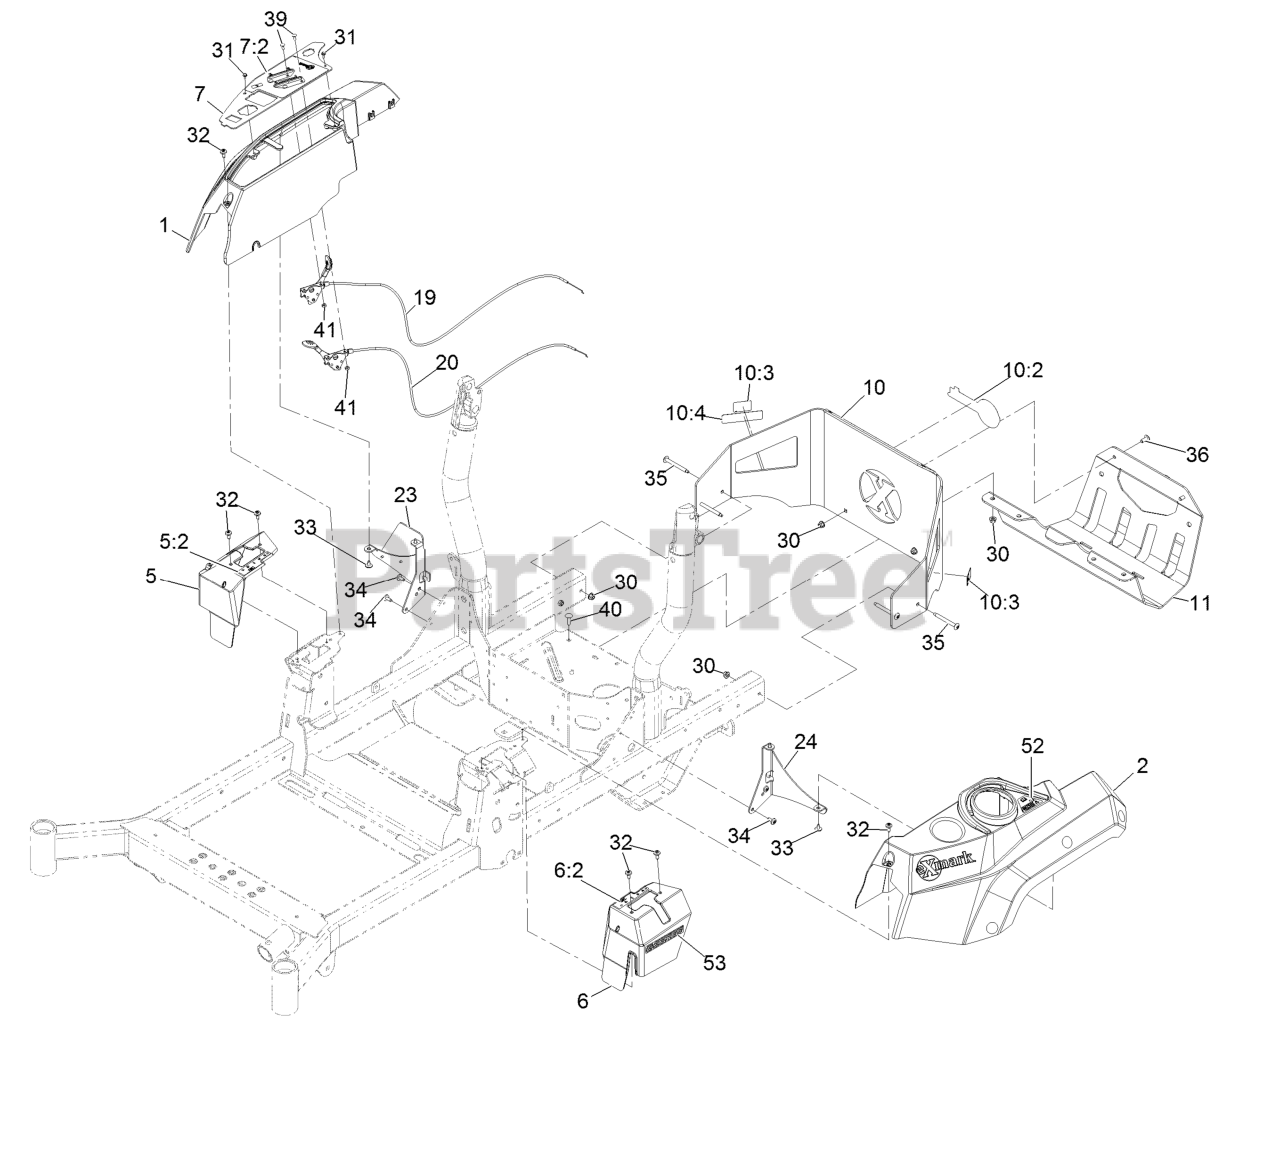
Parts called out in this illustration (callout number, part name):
1	Console, RH
2	Console, LH
5	Cover-Control, Motion (RH)
5:2	Decal-Control, Motion (RH)
6	Cover-Control, Motion (LH)
6:2	Decal-Control, Motion (LH)
7	Ctrl Panel ASM W/Decal
7:2	Decal-Control Panel
10	Rear Guard ASM
10:2	Decal-Exmark Logo
10:3	Decal-Warning
10:4	Decal-Arrester, Spark
11	Guard-Muffler
19	Cable-Control, Choke
20	Cable-Control, Throttle
23	Support-Console, RH
24	Bracket-Console, LH
30	Nut-Nyloc 5/16-18 Flg
31	Screw-HWH #10-14 X 1/2
32	Screw-1/4-20 X 1/2 Tf Torx Plus
33	Screw-HWH #10-14 X 1/2 Torx
34	Screw-1/4-20 X .65 Torx Plus
35	Screw-Truss HD 5/16-18 X 2 3/4 Torx Plus
36	Screw-Truss HD 5/16-18 X 3/4 Torx Plus
39	Bolt-Carriage #10-24 X 1/2
40	Bolt-Carriage 5/16-18 X 1 Sp
41	Nut-Nyloc #10-24
52	Decal-Fill, Fuel
53	Decal-E-Series
